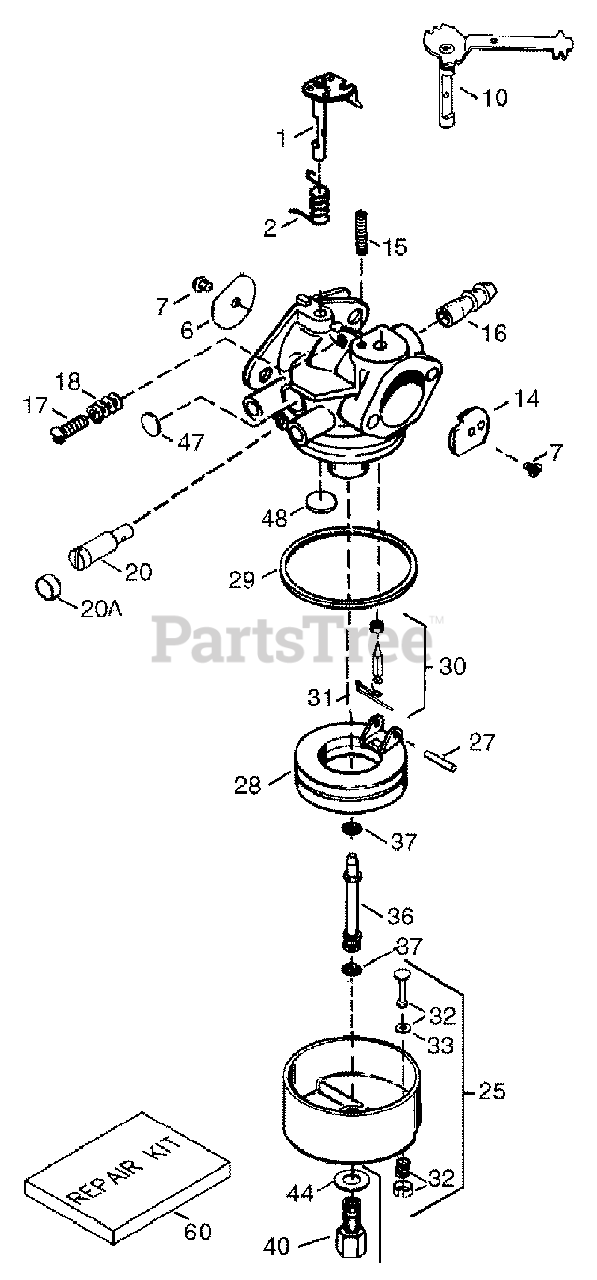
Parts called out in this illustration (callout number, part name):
1	Throttle Shaft & Lever Assembly
2	Throttle Return Spring
6	Throttle Shutter
7	Shutter Screw
10	Choke Shaft & Lever Assembly
14	Choke Shutter
15	Choke Positioning Spring
16	Fuel Fitting
17	Throttle Crack Screw/Idle Speed Screw
18	Tension Spring
20	Idle Restrictor Screw
20A	Idle Restrictor Screw Cap
25	Float Bowl Ass'y
27	Float Shaft
29	Float Bowl "O" Ring
30	Inlet Needle, Seat & Clip
31	Spring Clip
32	Bowl Drain Assembly
33	Drain Plunger Gasket
36	Main Nozzle Tube
37	"O" Ring, Main Nozzle Tube
40	High Speed Bowl Nut
44	Bowl Nut Washer
47	Welch Plug, Idle Mixture Well
48	Welch Plug, Atmospheric Vent
60	Repair Kit
